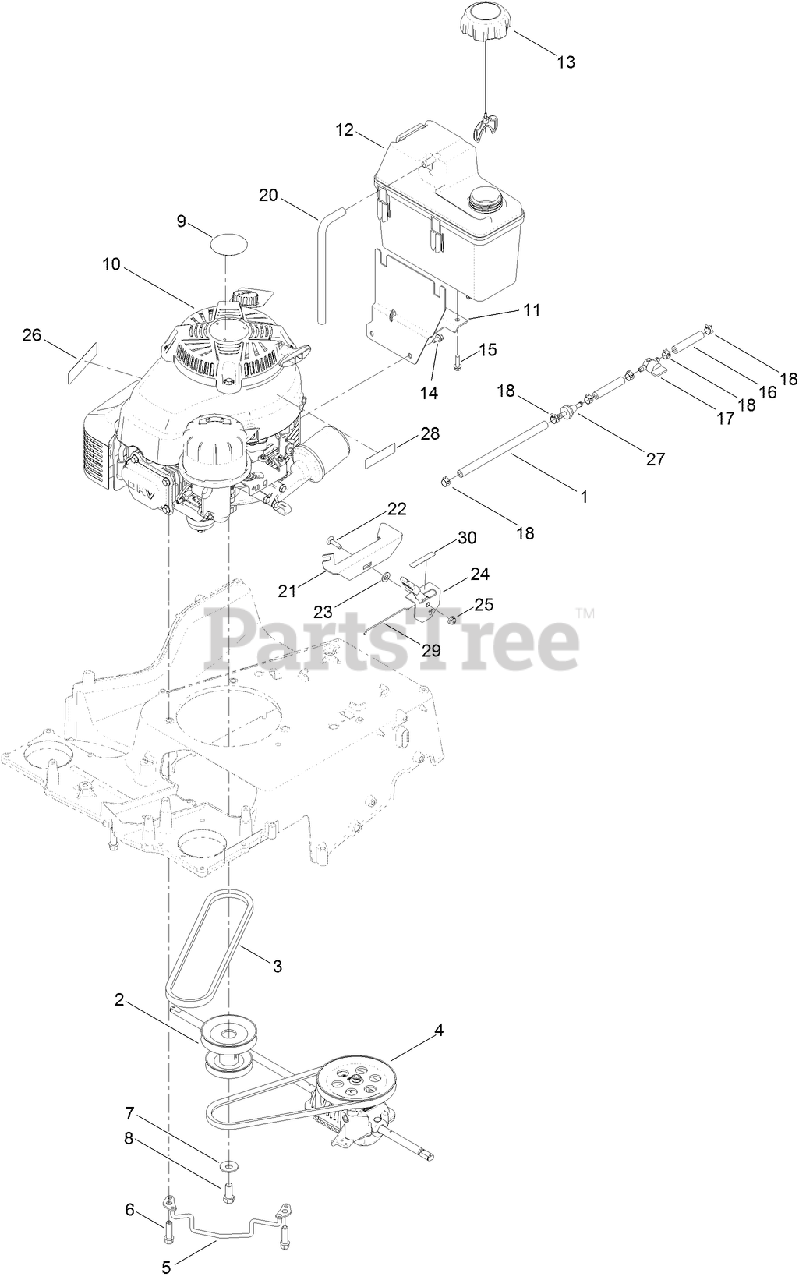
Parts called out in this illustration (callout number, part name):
1	HOSE-FUEL
2	PULLEY-ENGINE
3	V-BELT
5	GUIDE-BELT
6	Screw-HWH 3/8-16 x 1 1/4 Taptite
7	Washer-Spring Disc
8	Screw-HH 7/16-20 x 1
9	Decal-Recoil
11	MOUNT-TANK
12	TANK-FUEL
13	CAP-FUEL
14	SCREW-HWH
15	Screw-HWH 1/4-10 x .82 Plastite
16	Hose-Fuel Line 2 1/2"
17	Valve-Fuel
18	Clamp-Hose
20	HOSE-VENT, CANISTER
21	BRACKET-MOUNT, THROTTLE
22	Bolt-Carriage 1/4-20 x 1
23	Washer-5/16 SAE
24	CONTROL-THROTTLE
25	Nut-Nyloc 1/4-20 Flg
26	DECAL-ARRESTER, SPARK
27	FILTER-FUEL
28	DECAL-WARNING, ENGINE
29	WIRE-CONTROL
30	DECAL-THROTTLE, CHOKE
